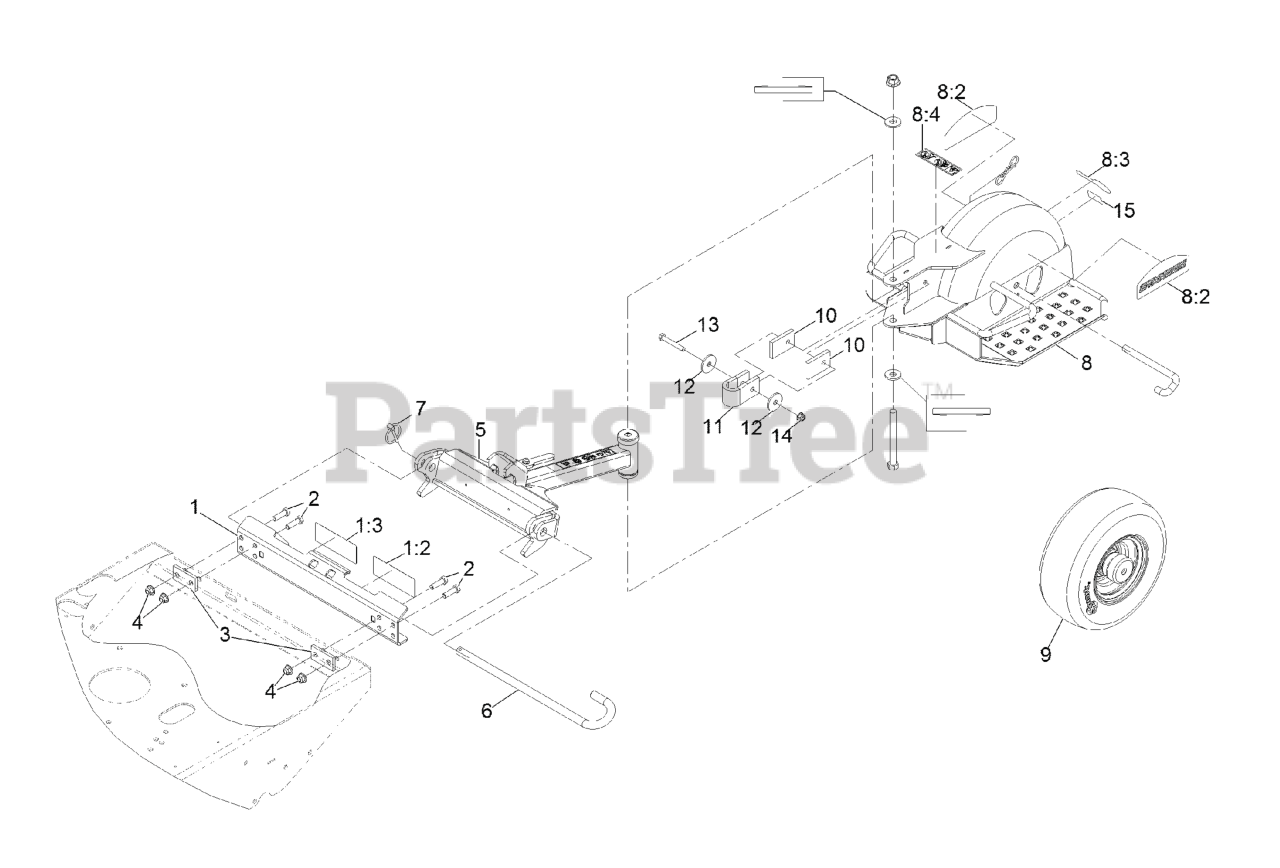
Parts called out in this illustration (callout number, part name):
1	ASM, MOUNT PLATE
1:2	DECAL-BELT DRIVE WARNING
1:3	DECAL-WARNING, SULKY
2	SCREW-HH
3	PLATE,BACK-UP (PLATED)
4	NUT-HF, NI
5	ASM, DRAW BAR
6	PIN, PIVOT
7	PIN-LYNCH
8	ASM-SULKY FRAME W/ DECALS
8:2	DECAL, STANDON
8:3	DECAL, EXMARK
8:4	DECAL-WARNING HAND PINCH
9	ASM, WHEEL AND BEARINGS
10	PAD,STOP
11	STOP, ROTATION
13	SCREW-HH
14	NUT-HF, NI
15	Decal-Patent Ttco.Com
